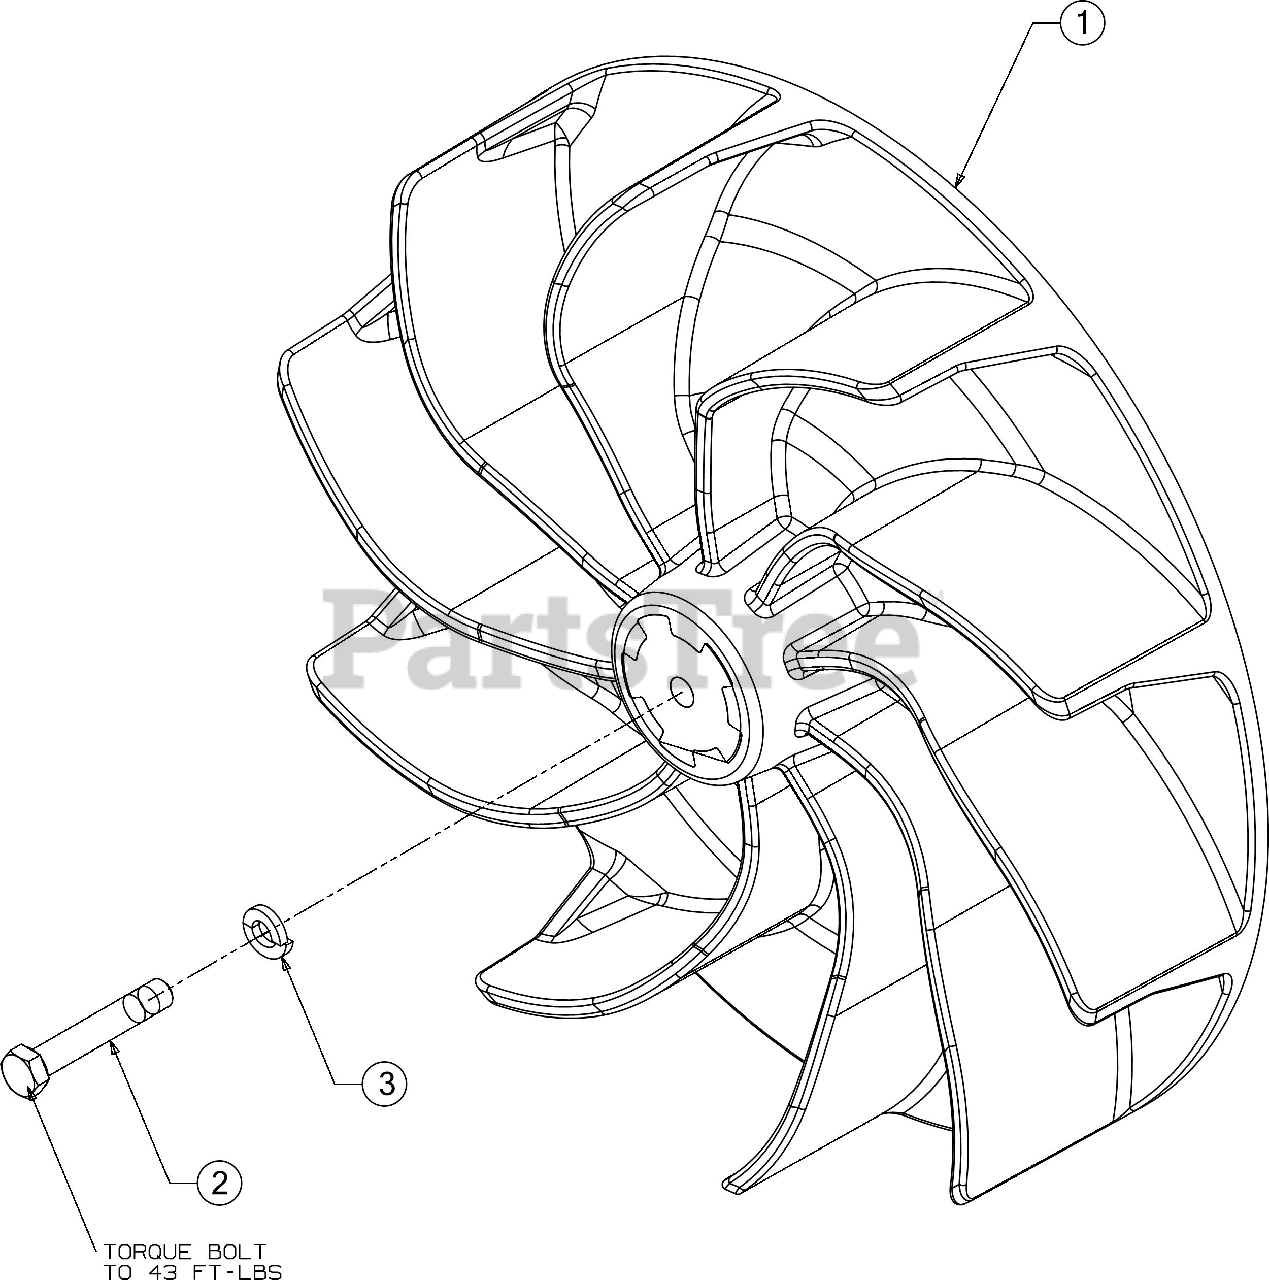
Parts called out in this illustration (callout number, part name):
1	BLOWER IMPELLER ASSEMBLY
2	SCREW 3/8-24X2.25 GR8
3	LOCK WASHER 3/8HD
